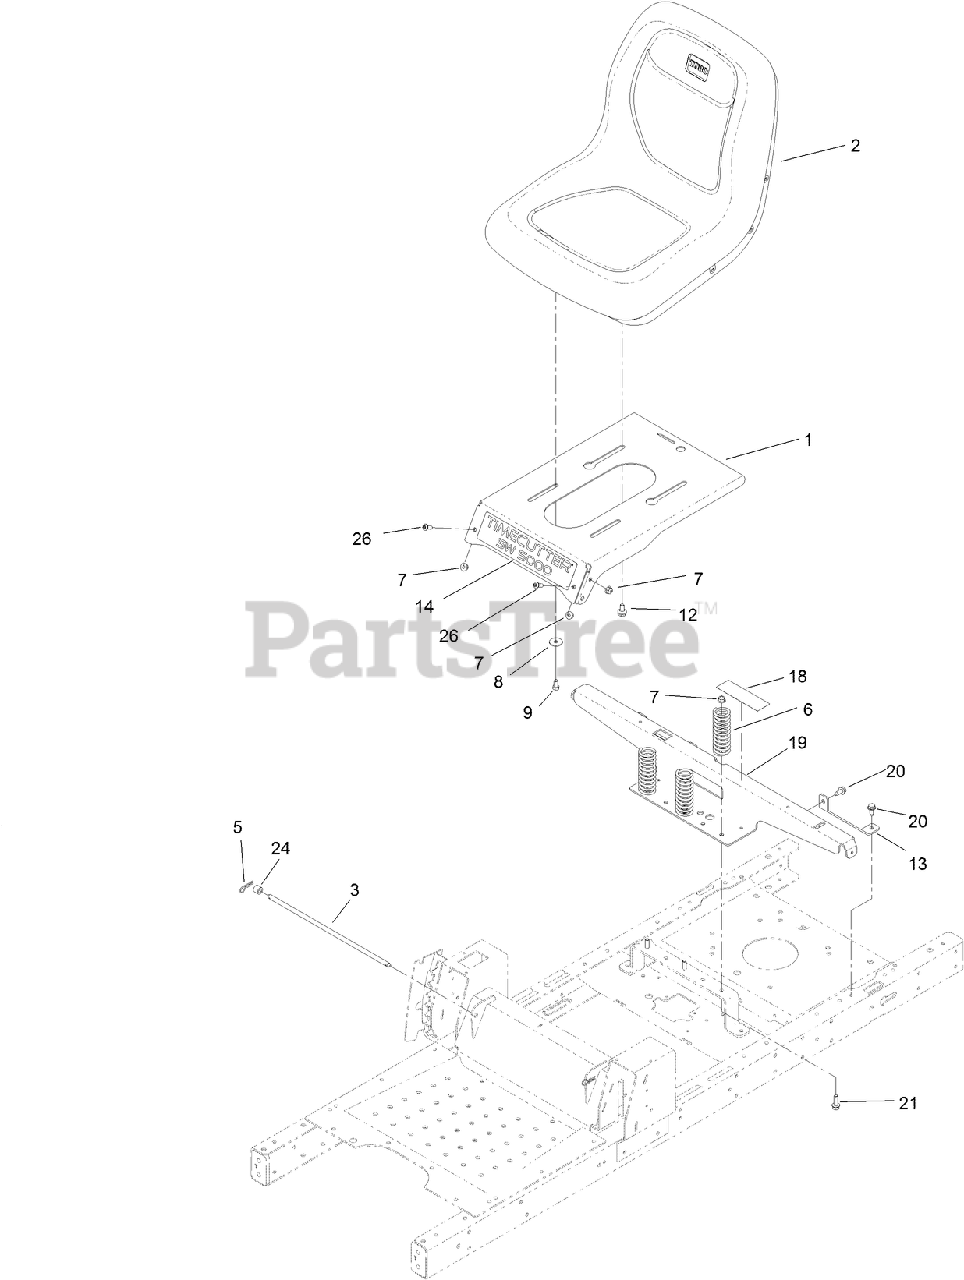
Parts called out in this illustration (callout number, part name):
1	PAN-SEAT
2	SEAT-18 INCH
3	ROD-STOP
5	PIN-COTTER
6	SPRING-COMPRESSION
7	NUT-HF, NI
8	WASHER-PIVOT
9	SCREW-HH
12	BOLT-SHOULDER,HFH
13	SUPPORT-TANK, REAR
14	DECAL-TIMECUTTER
18	DECAL-SERVICE, CE
19	SUPPORT-POD, WIDE
20	SCREW-HWHTF
21	SCREW-HHF
24	BUSHING-LEVER, LIFT
26	SCREW-HSBH
